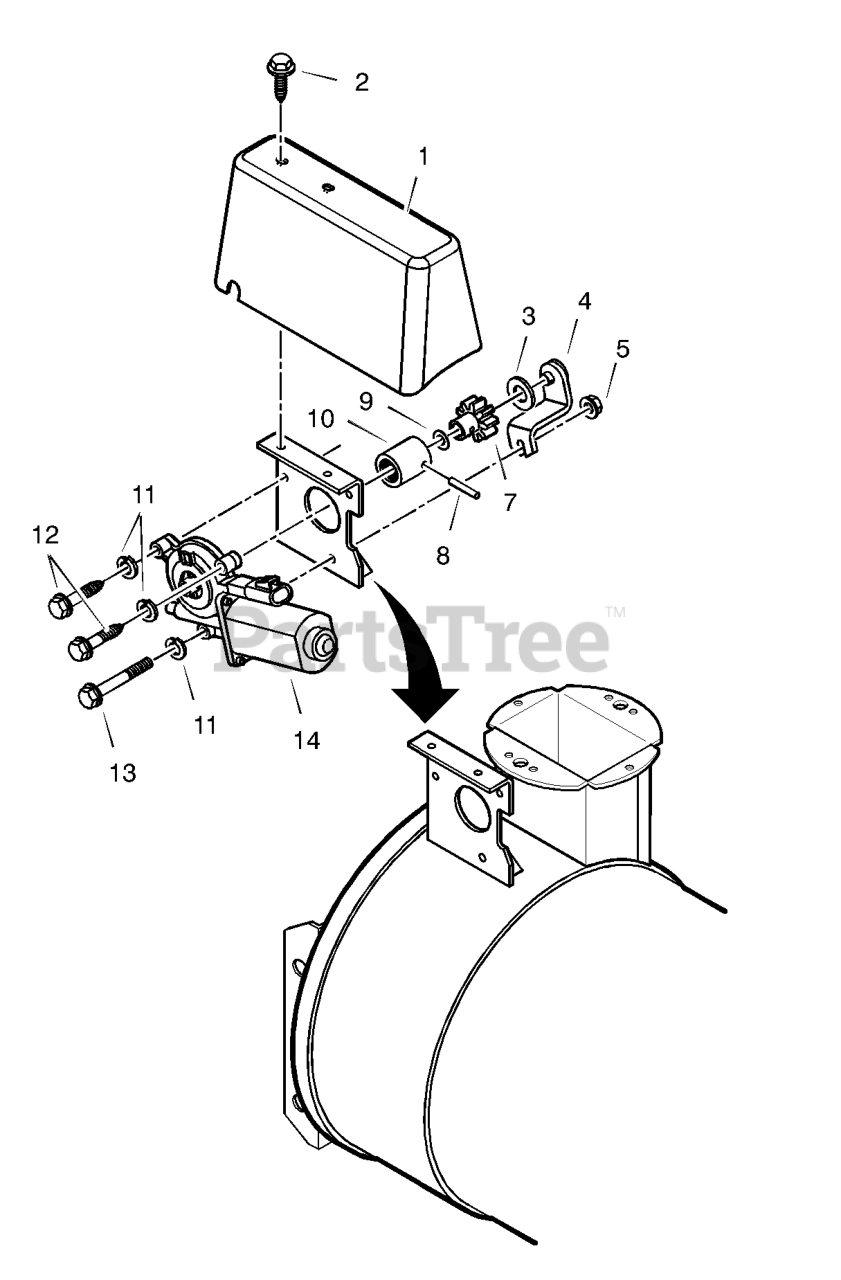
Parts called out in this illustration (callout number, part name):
1	COVER, MOTOR
3	WASHER
4	BRACE, CHUTE GEAR
8	PIN, SPRING
9	RING, RETAINER
10	ADAPTER
11	WASHER
13	BOLT, HEX
14	MOTOR, ELECTRIC
